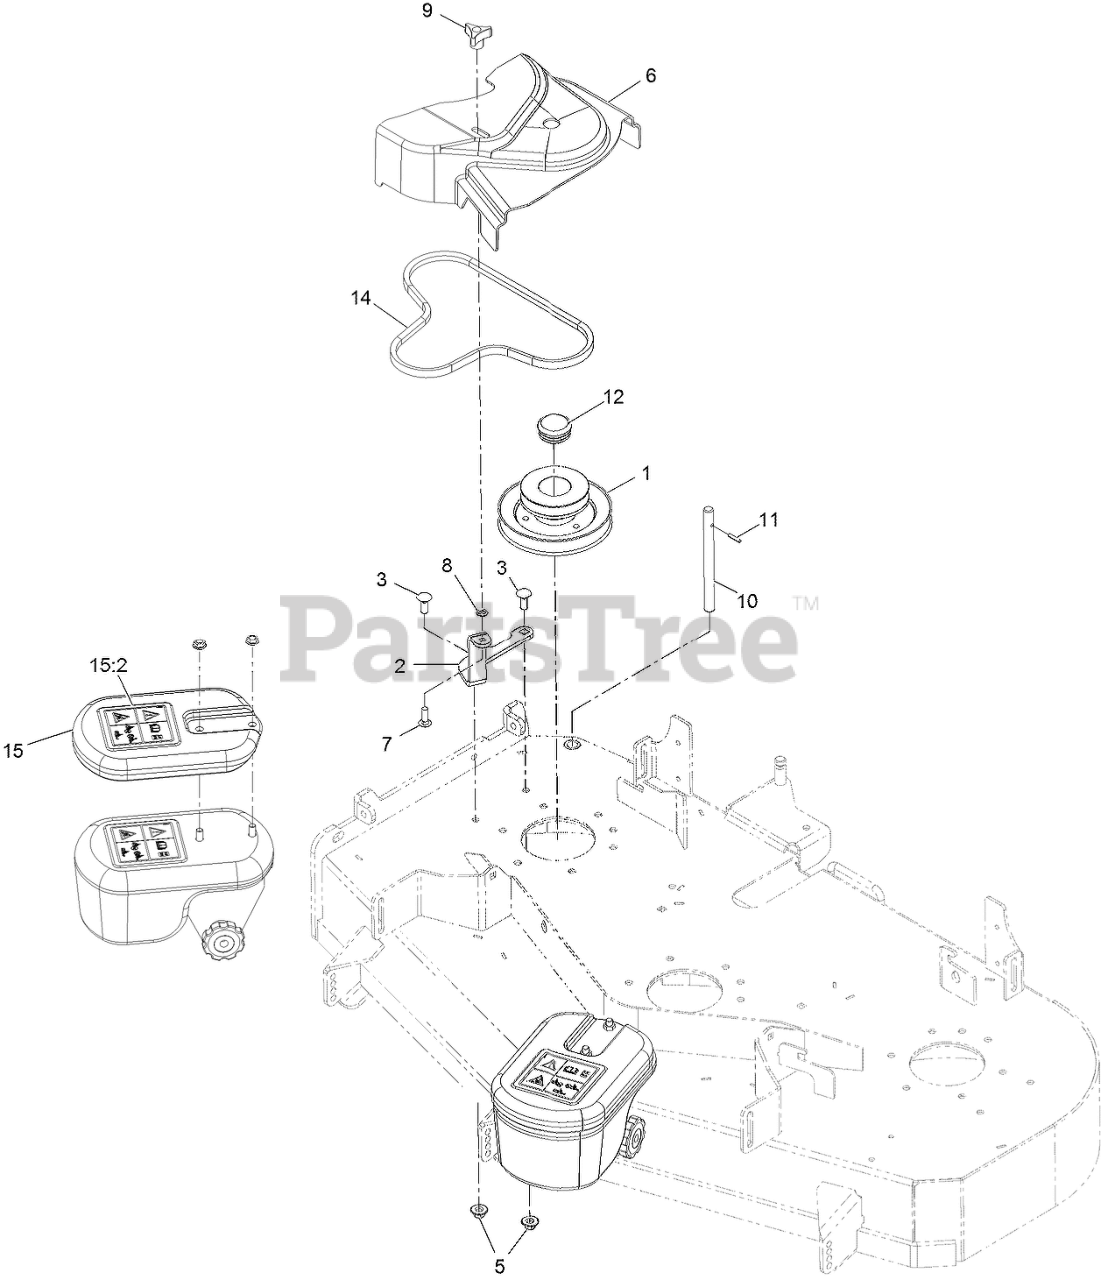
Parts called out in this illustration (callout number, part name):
1	JACKSHAFT-UV DRIVE, 484 S
2	BRACKET, SMALL UV BELT CO
3	BOLT-CARR
5	Nut-Nyloc 3/8-16 Flg
6	COVER-BELT, UV 48
7	BOLT-CARR
8	RING-RETAINING, BOLT
9	KNOB-3 PRONG
10	SHAFT-CATCHER, GRASS
11	PIN-ROLL
12	PLUG-ROUND PLASTIC
14	BELT-BLOWER
15:2	DECAL-WARNING, TRACTION
